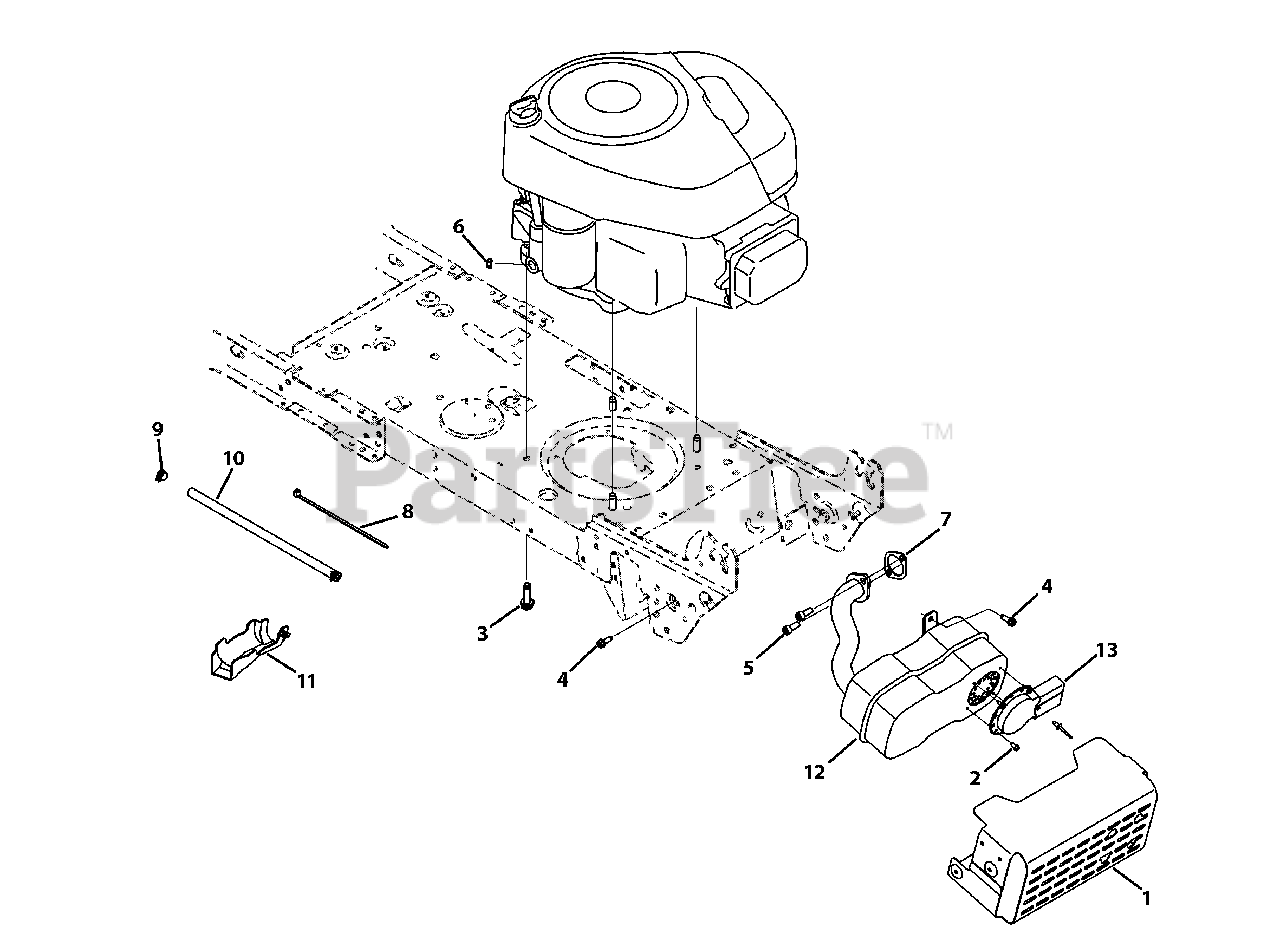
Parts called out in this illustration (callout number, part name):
1	Muffler Shield Assembly with Weld
2	Screw, 8-18 x .500
3	Screw, 3/8-16 x 1.0
4	Screw, 1/4-20 x .750
5	Socket Screw, 5/16-18 x .750
6	Sems Nut, 1/4-20
7	Exhaust Gasket, 10 HP Briggs
8	Cable Tie
9	Clamp Hose, .490 diameter
10	Fuel Hose, Low Permeation
11	Oil Drain Sleeve
12	Muffler, Single Inlet
13	Muffler Deflector Long
